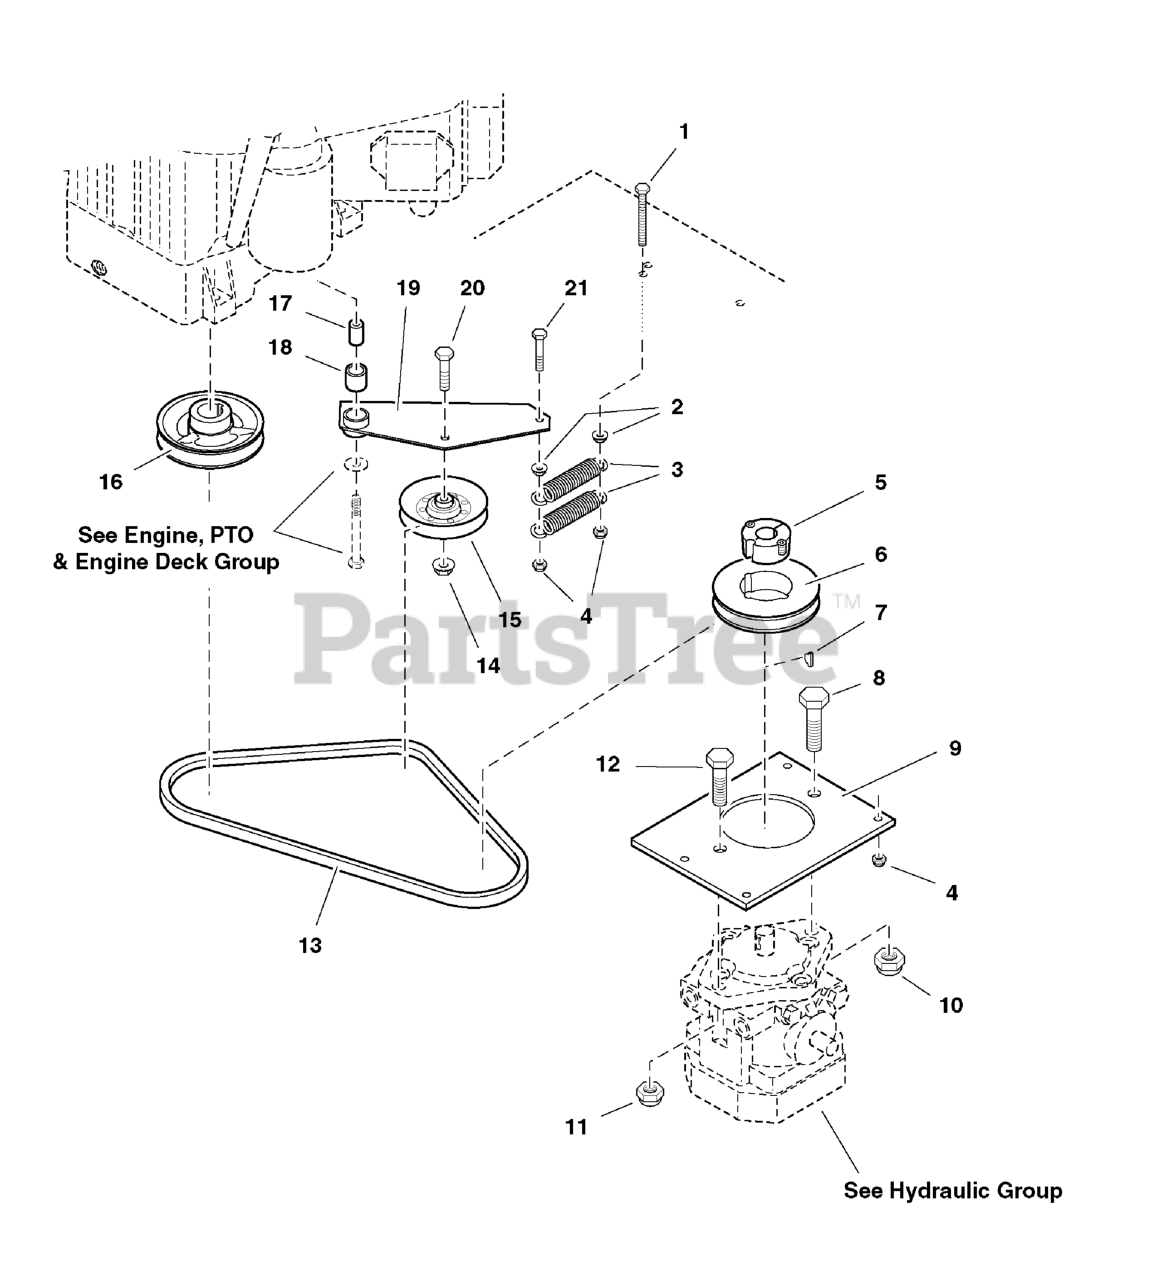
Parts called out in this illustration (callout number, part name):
1	BOLT, 5/16-18 x 3-1/2 TFL
2	NUT, 5/16-18 HEX SERRATED FLANGE (SMALL)
3	SPRING, Extension
4	NUT, 5/16-18 Hex Nylon Lock
5	BUSHING, Tapered Hub
6	PULLEY, Tapered Hub
7	KEY, #61 Woodruff
8	BOLT, 1/2-20 X 1-3/4" GD8 CZ
9	PLATE, Pump Mount
10	NUT, Hex, Nylon Lock, 1/2-20
11	NUT, 7/16-14 Hex Nylon Lock
12	BOLT, 7/16-14 x 1-1/2
13	BELT
14	NUT, 3/8-16 Hex Serrated Flange
15	PULLEY, Idler
16	PULLEY, Pump Drive
17	SPACER, .32 x .75 x 1.06
18	BUSHING, Brass
19	IDLER ARM ASSEMBLY, Complete
20	BOLT, 3/8-16 X 1-3/4" GD5 CZ
21	BOLT, 5/16-18 x 1-3/4
